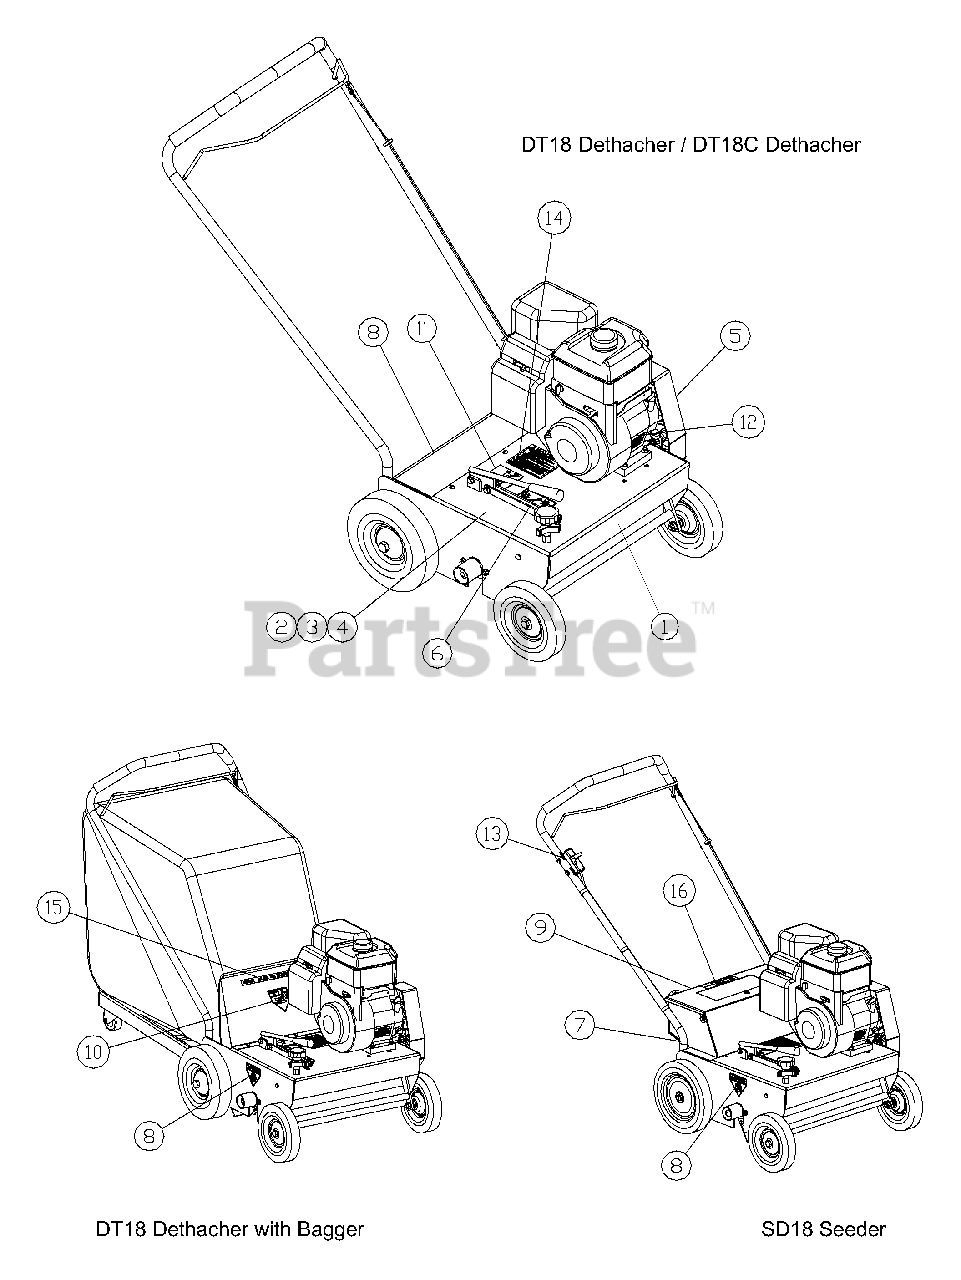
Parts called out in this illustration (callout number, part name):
1	Decal, Husqvarna Logo
2	Decal, DT18C Dethacher
3	Decal, DT18 Dethacher
4	Decal, SD18 Seeder
5	Decal, Husqvarna Crown
6	Decal, Height Adjusment
7	Decal, Gage Dial
8	Decal, Danger Foot
9	Decal, Seed Application
10	Decal, Danger Chute
12	Decal, Warning Carbon Monoxide
13	Decal, Open / Close,
14	Decal, Caution List
15	Decal, Caution Catcher
16	Decal, HOT Seeder Lid
